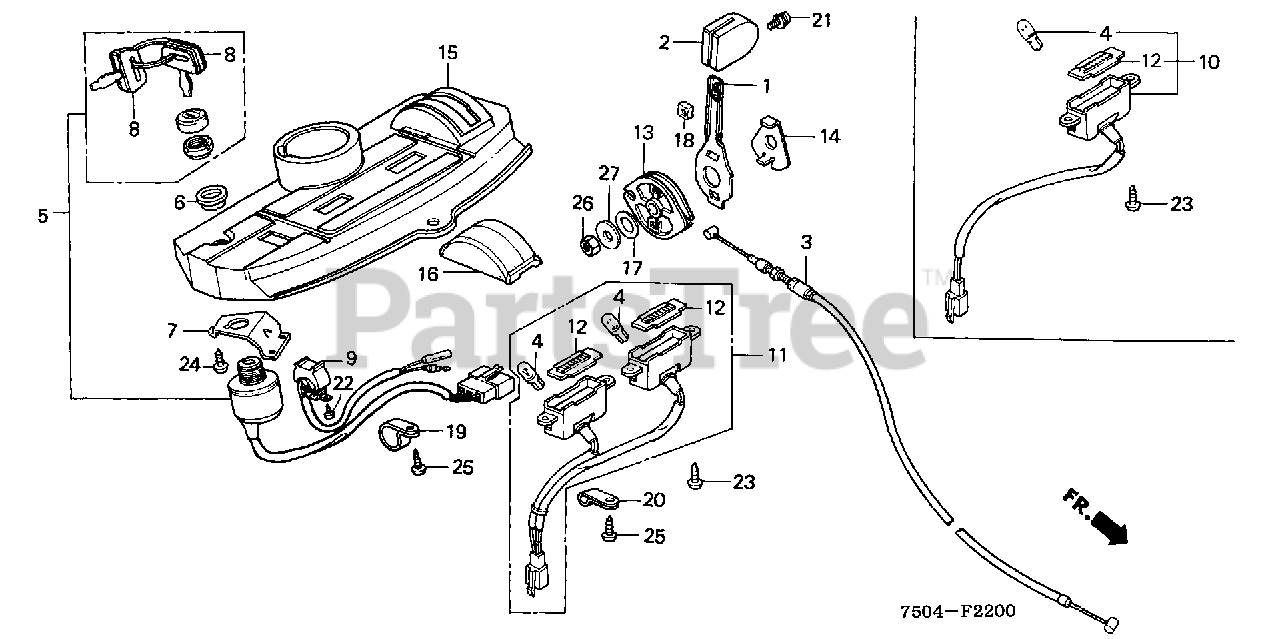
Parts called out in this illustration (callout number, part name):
1	LEVER, THROTTLE (NOT AVAILABLE)
2	KNOB, THROTTLE LEVER *NH105* (MAT BLACK)
3	CABLE, THROTTLE
4	BULB, WEDGE BASE (12V/3W) (STANLEY)
5	SWITCH ASSY., COMBINATION
8	KEY ASSY., COMBINATION SWITCH
9	SWITCH ASSY., LIGHTING
11	SOCKET ASSY., LAMP
13	REEL, CABLE
14	STOPPER, REEL
15	PANEL, INSTRUMENT *NH105* (MAT BLACK)
16	SEAL, THROTTLE LEVER
17	WASHER (11MM)
18	NUT, SQUARE (4MM)
19	CLIP (14MM)
20	CLIP, WIRE HARNESS
21	SCREW-WASHER (4X8)
22	SCREW, TAPPING (3X8)
23	SCREW, TAPPING (4X12)
25	SCREW, TAPPING (4X10)
26	NUT, HEX. (6MM)
27	WASHER, PLAIN (6MM)
